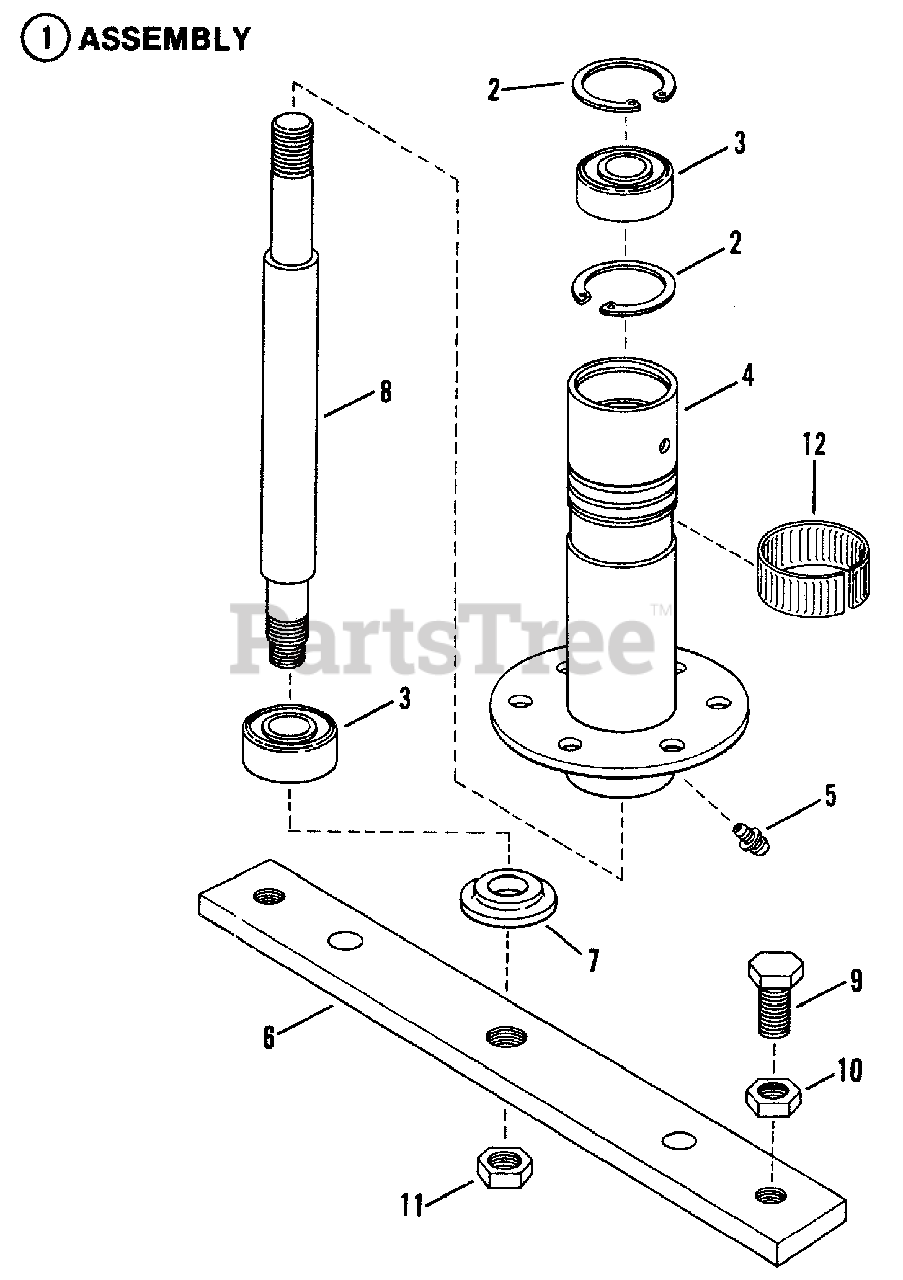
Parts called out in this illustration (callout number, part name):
1	ASSEMBLY, Spindle Housing
2	RING, Retaining
3	BEARING, Spindle
4	HOUSING, Spindle
5	FITTING, Lube (Press fit for .187 hole-no ball)
6	HOLDER, Blade
7	WASHER, Spindle
8	SPINDLE, Shaft (10.237" Long)
9	SCREW, 1/2-20 x 1" Hex Head Cap (Gr. 5)
10	NUT, 1/2-20 Hex Jam
11	NUT, 5/8-18 Hex Lock
12	RING, Tolerance
13	KIT, Blade Holder
